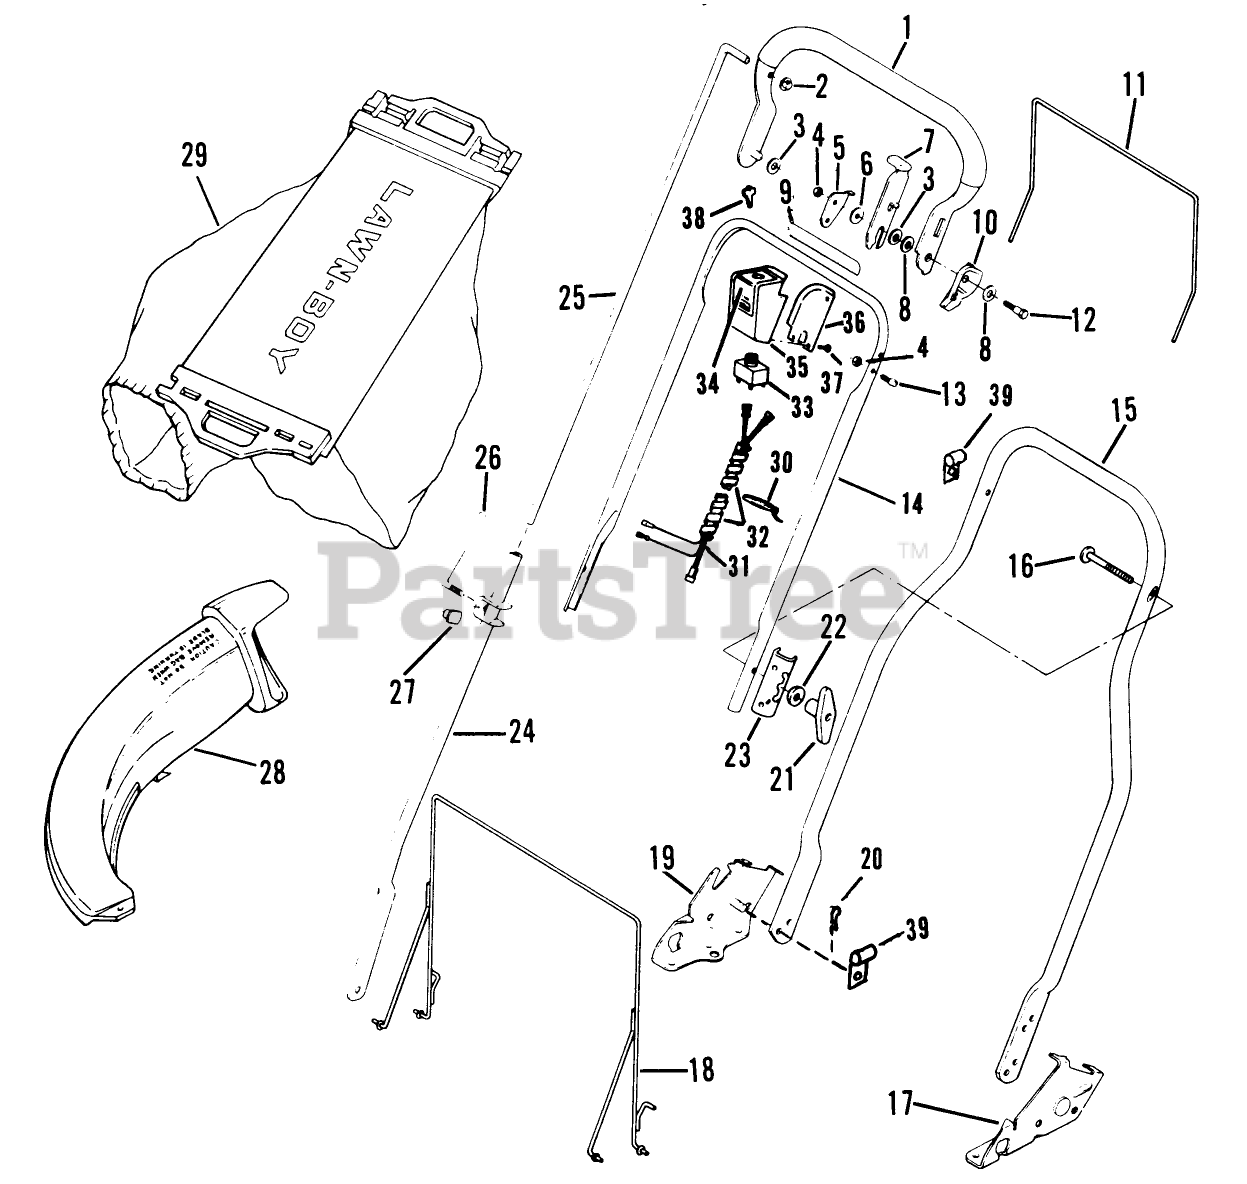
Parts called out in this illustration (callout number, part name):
3	WASHER M
4	LOCKNUT E
5	HANDLE STOP
6	WASHER
9	DISCOUNTED
11	HANGER
12	BOLT PIONEER
13	SCREW-HANDLE STOP
14	HANDLE
19	HANDLE BRACKET
20	HAIR PIN
21	NUT-WING
22	WASHER-CURVED
23	BRACKET R/B 613462
25	ROD CONTROL
35	HOUSING SWITCH
